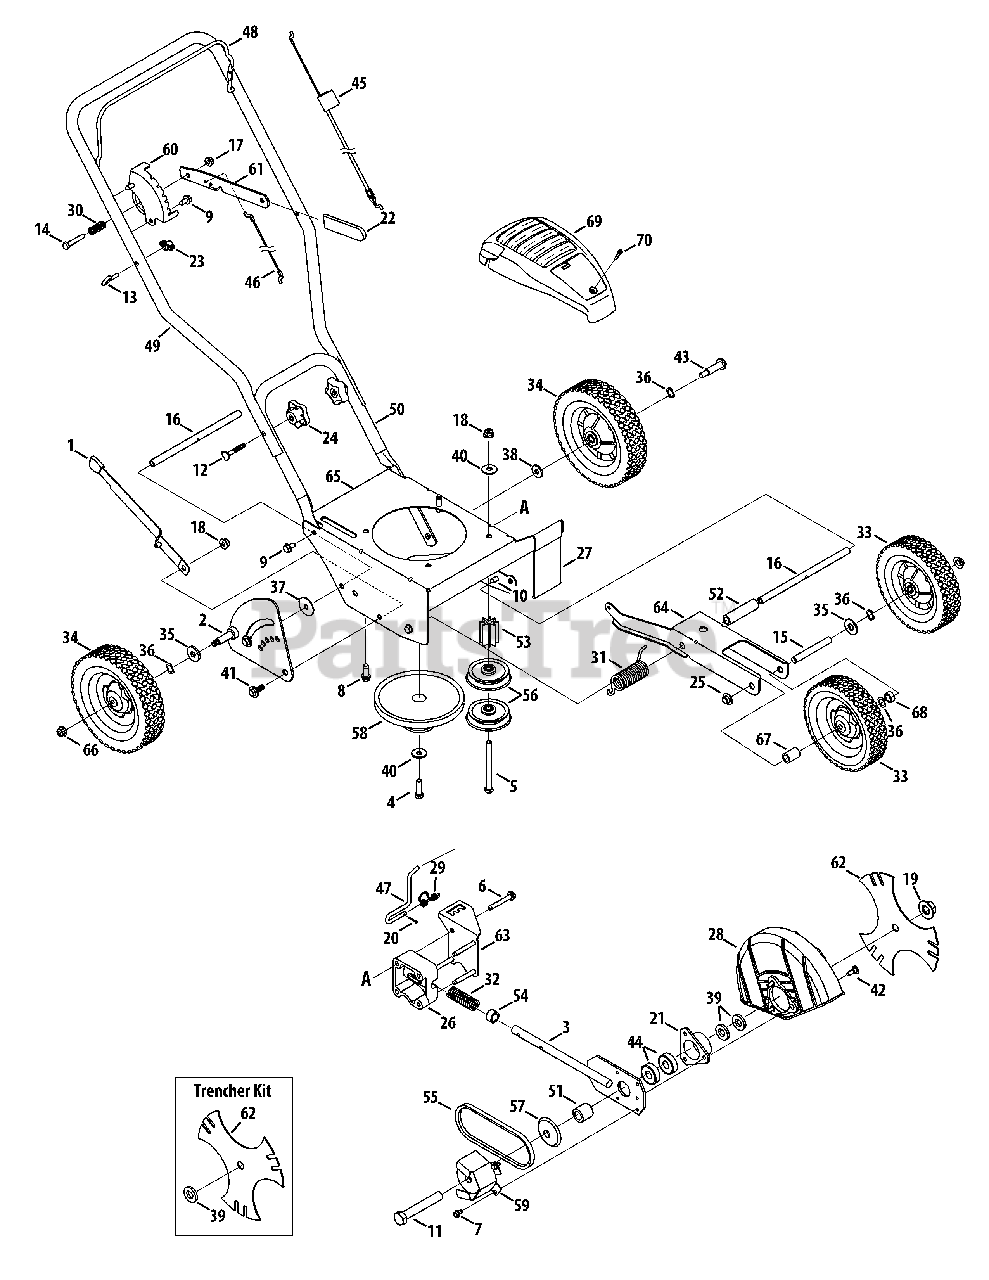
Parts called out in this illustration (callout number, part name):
1	Curb Height Adjustment Lever
2	Curb Height Adjuster Plate
3	Blade Plate Assembly
4	Screw 3/8-24
5	Screw 3/8-16
6	Hex Screw, 5/16-18
7	Self-tapping Screw, 1/4-20
8	Screw, 3/8-16
9	Hex Screw, 5/16-12
10	Hex Screw 5/16-18
11	Hex Screw, 5/8-18
12	Carriage Bolt, 5/16-18
13	Rope Guide (Eye Bolt)
14	Hex Screw, 5/16-18
15	Axle Shaft .50x6.65
16	Frame Spacer .50x9.25
17	Lock Flange Nut, 5/16-18
18	Flange Nut 3/8-16
19	Flange Nut, 5/8-18
20	Clevis Pin 3/32 x .625
21	Bearing Cup
25	Push Cap 1/2" rod
26	Bearing Block
27	Debris Guard
28	Blade Guard
29	Double Torsion Spring
30	Compression Spring
31	Torsion Spring
32	Compression Spring
33	Wheel 7 x 1.75 T-Tread
34	Wheel 8 x 1.75 T-Tread
35	Flat Washer, .531 x 1.25 x .181
36	Wave Washer .531 x .781 x .013
37	Flat Washer, .385 x 1.5 x .075
38	Flat Washer .385 x 1.0 x .135
39	Flat Washer .635x1.24x.181
40	Bell Washer,.396 x 1.140
41	Shoulder Screw, 3/8-16
42	Shoulder Screw
43	Shoulder Screw, 3/8-16
44	Bearing, .625 ID x 1.57 OD
45	Control Cable
46	Wheel Adjustment Cable
47	Blade Adjustment Rod
48	Bail Handle
51	Spacer, .63 x 1.12 x 1.06
53	Pulley Mount Spacer
54	Spacer, .64 x.88 x .50
56	Flat Idler Pulley, 2.5 OD
58	Combination Flywheel Pulley
61	Depth Index Lever
62	Tri-Star Blade
63	Bracket Plate
64	Dual Wheel Bracket
66	Flange Lock Nut, 3/8-16
67	Spacer., .525 x .775 x .93
68	Spacer., .505ID x .88OD x .440
69	Engine Shroud
70	Screw, #10-16 x 1.25
